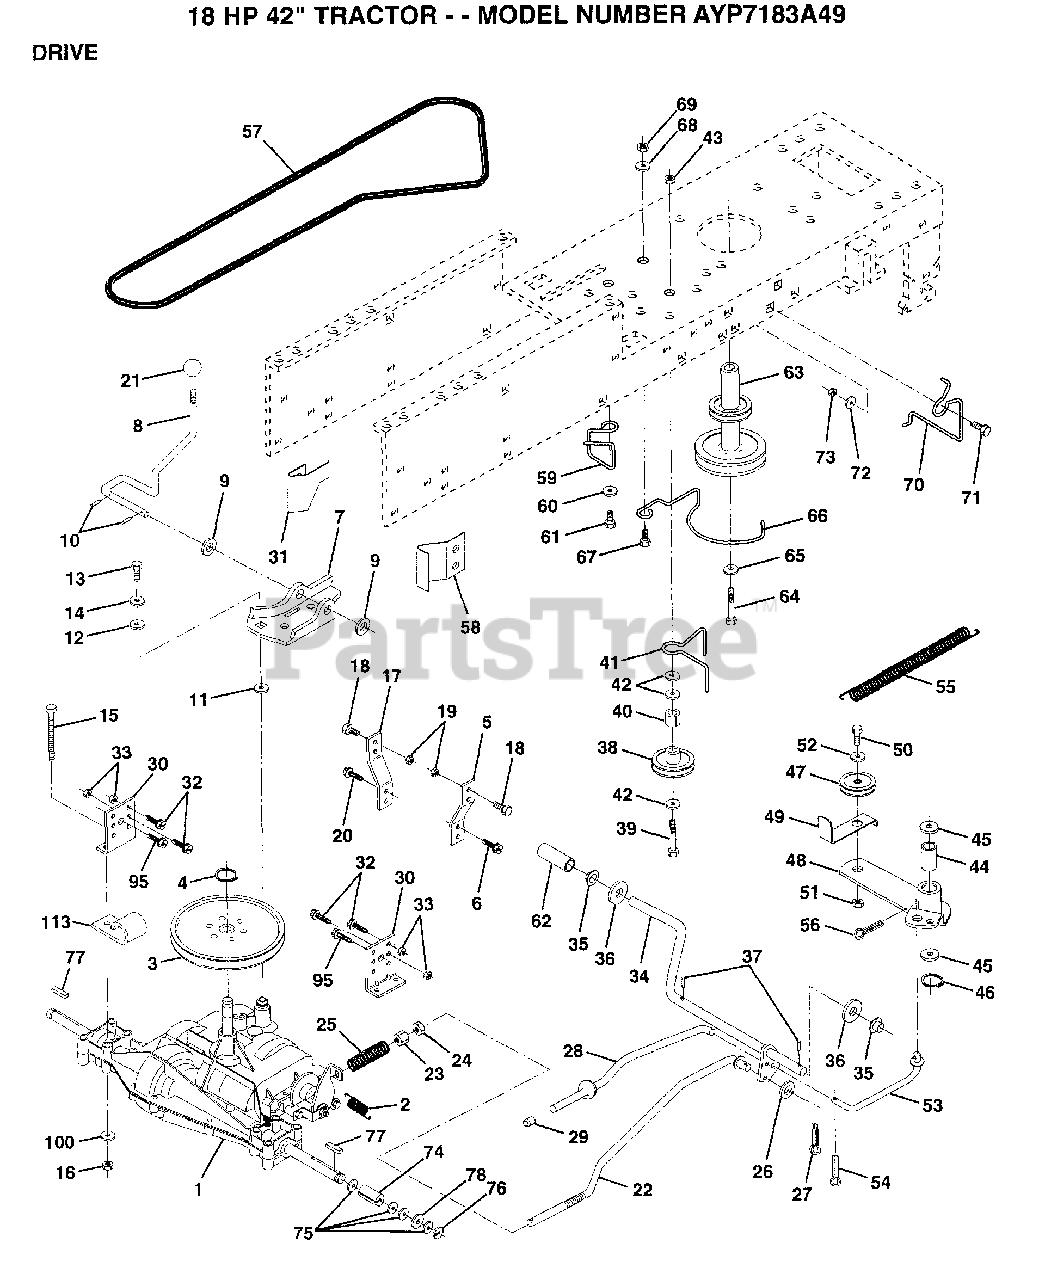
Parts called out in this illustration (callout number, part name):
3	PULLEY TRANS
5	STRAP TORQUE
6	SCREW
10	PIN COTTER 1/8
11	WASH-SHFT PLT LT
12	WASHER
14	LOCKWASHER
15	BOLT HEX
17	STRAP TORQUE
18	BOLT
19	NUT
20	SCREW
21	KNOB T (1/2-HOLE)
22	BRAKE ROD
23	NUT
24	NUT
25	SPRING ROD LT
26	WASHER
27	COTTER PIN
28	ROD PARK BRAKE
30	TRANSAXLE MTG BKT
31	"KEEPER,BELT LH T"
32	BOLT
33	NUT
35	NYLON BEARING
36	WASHER LT
38	PULLEY.IDLER.FLAT
39	BOLT
40	SPACER T
41	BELT KEEPER LT
42	WASHER
43	NUT
44	"LY, BEARING"
45	WASHER LT
46	KLIP RING
48	ARM IDLER
49	RETAIN BELT
52	WASHER
53	"LINK, CLUTCH T"
54	COTTER PIN
55	"SPRING, RETURN LT"
56	COTTER PIN
58	"KEEPER,BELT RH T"
59	KEEPER BELT CNTSP
60	WASHER
61	SCREW
62	PEDAL COVER T
63	PULLEY.ENGINE
64	BOLT
65	LOCKWASHER
66	KEEPER.BELT.ENG.L
67	BOLT
68	WASHER
70	KEEPER BELT ENG
71	BOLT
72	WASHER
74	SPACER LT
75	WASHER
76	E-RING LT
77	SQUARE KEY
78	WASHER
80	ARM SHIFT TRANS
81	SHAFT ASM.SHIFT
82	"SPRING,TORSION"
83	WASHER
84	TIE ROD
85	NUT 1/4-28
86	BUSHING
87	WASHER D
88	KLIP RING
90	NUT
95	SCREW
100	WASHER M
113	CLIP T
